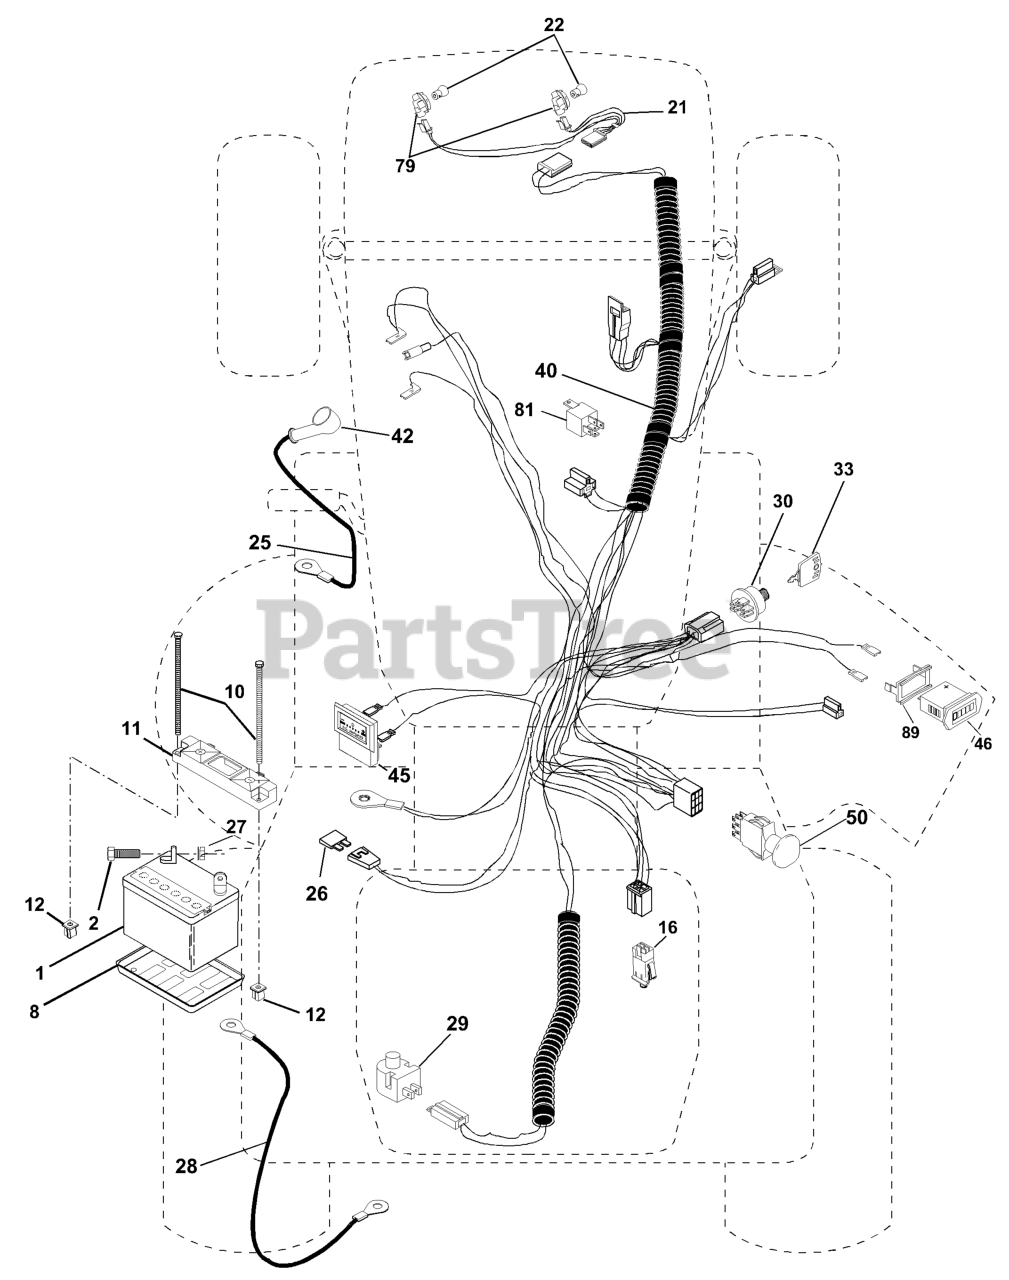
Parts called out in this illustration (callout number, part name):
1	BATTERY 12V .35 AMP
2	BOLT.HEX.1/4.X.3/4.DICHROMATE
8	BATTERY TRAY T
10	BOLT 1/4-20 X 7.5
11	BATTERY HOLDDOWN FRONT MOUNT
12	NUT, PUSH NYLON 1/4" BATTERY
16	SWITCH INTERLOCK
21	HARNESS ASM LIGHT
25	CABLE, BATTERY
27	NUT
28	CABLE, GROUND
29	PLUNGER SWITCH (COLOR:OLIVE)
30	IGNITION SWITCH
33	KEY MLD GEN DELTA
40	HARNESS, IGNITION
42	COVER.TERMINAL.RED
46	HOUR METER
50	RP.PTO.SWITCH.8 TERMINAL.BLACK
79	BULBHOLDER ASM
81	RELAY.ASSY.T
89	BRACKET SNAP-IN HOURMETER
